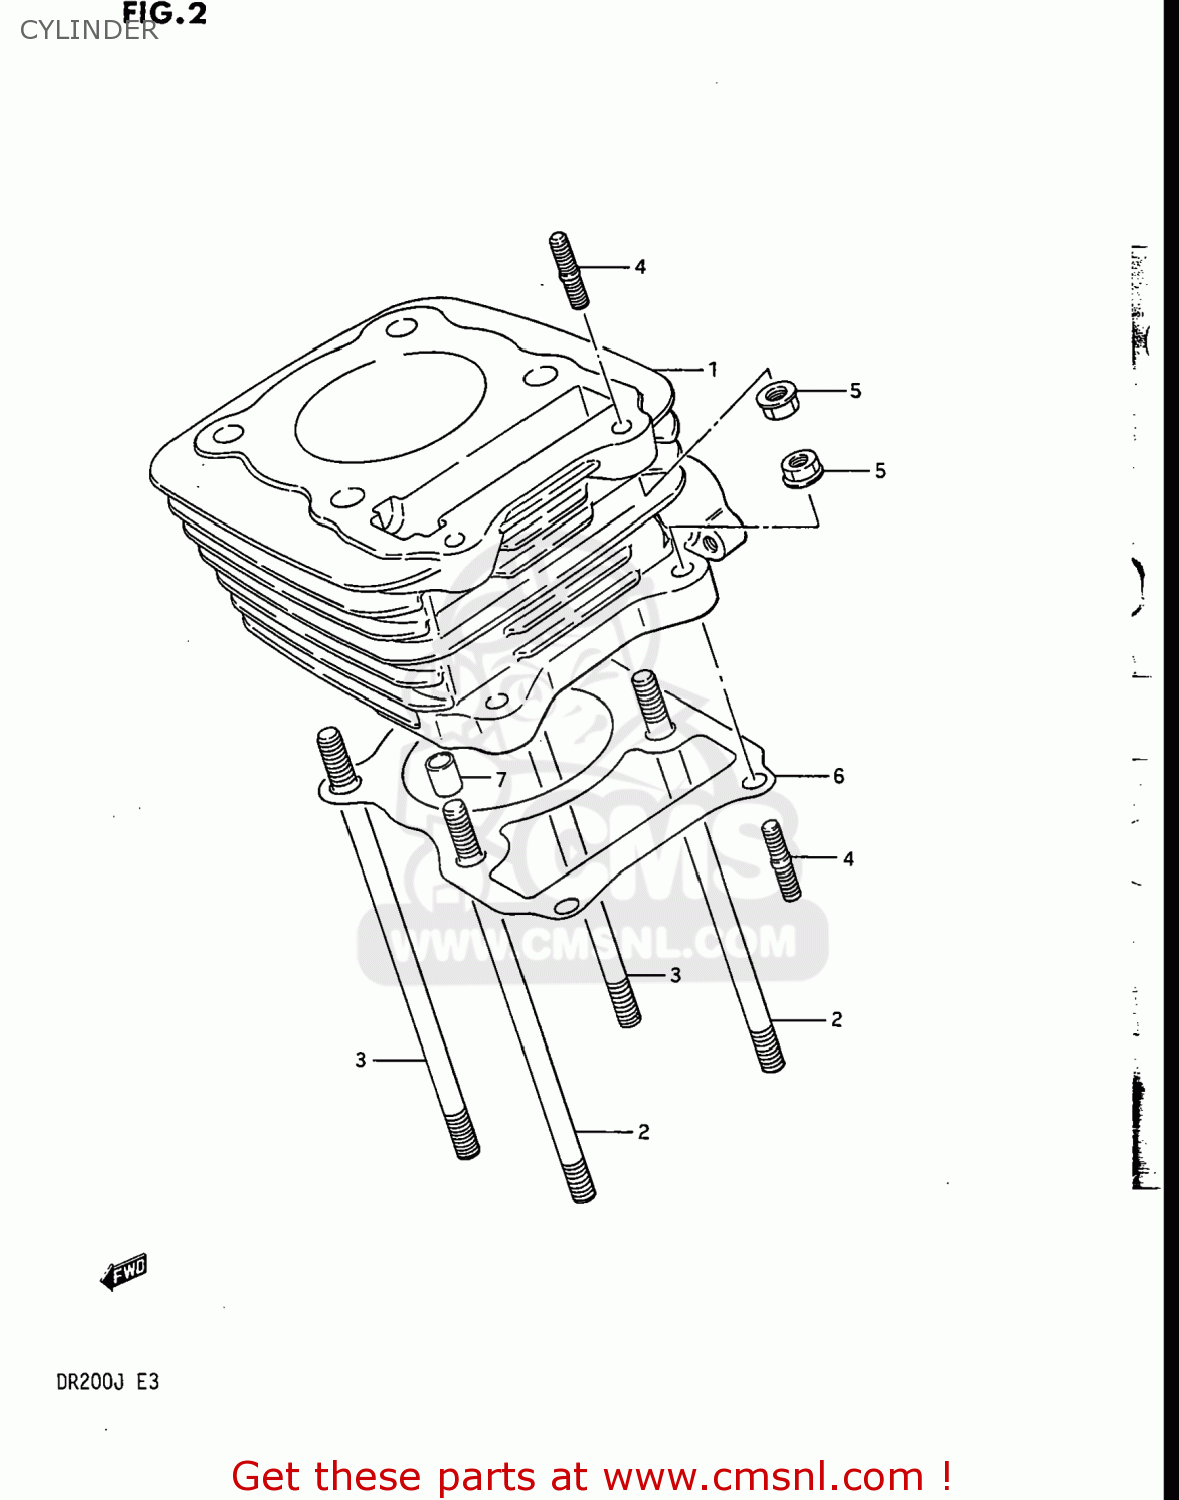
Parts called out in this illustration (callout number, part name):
1	CYLINDER
2	BOLT,STUD
3	BOLT,STUD(8X167)
4	STUD 6X25
5	NUT 6MM
6	GASKET,CYLINDER (MCA)
7	PIN
